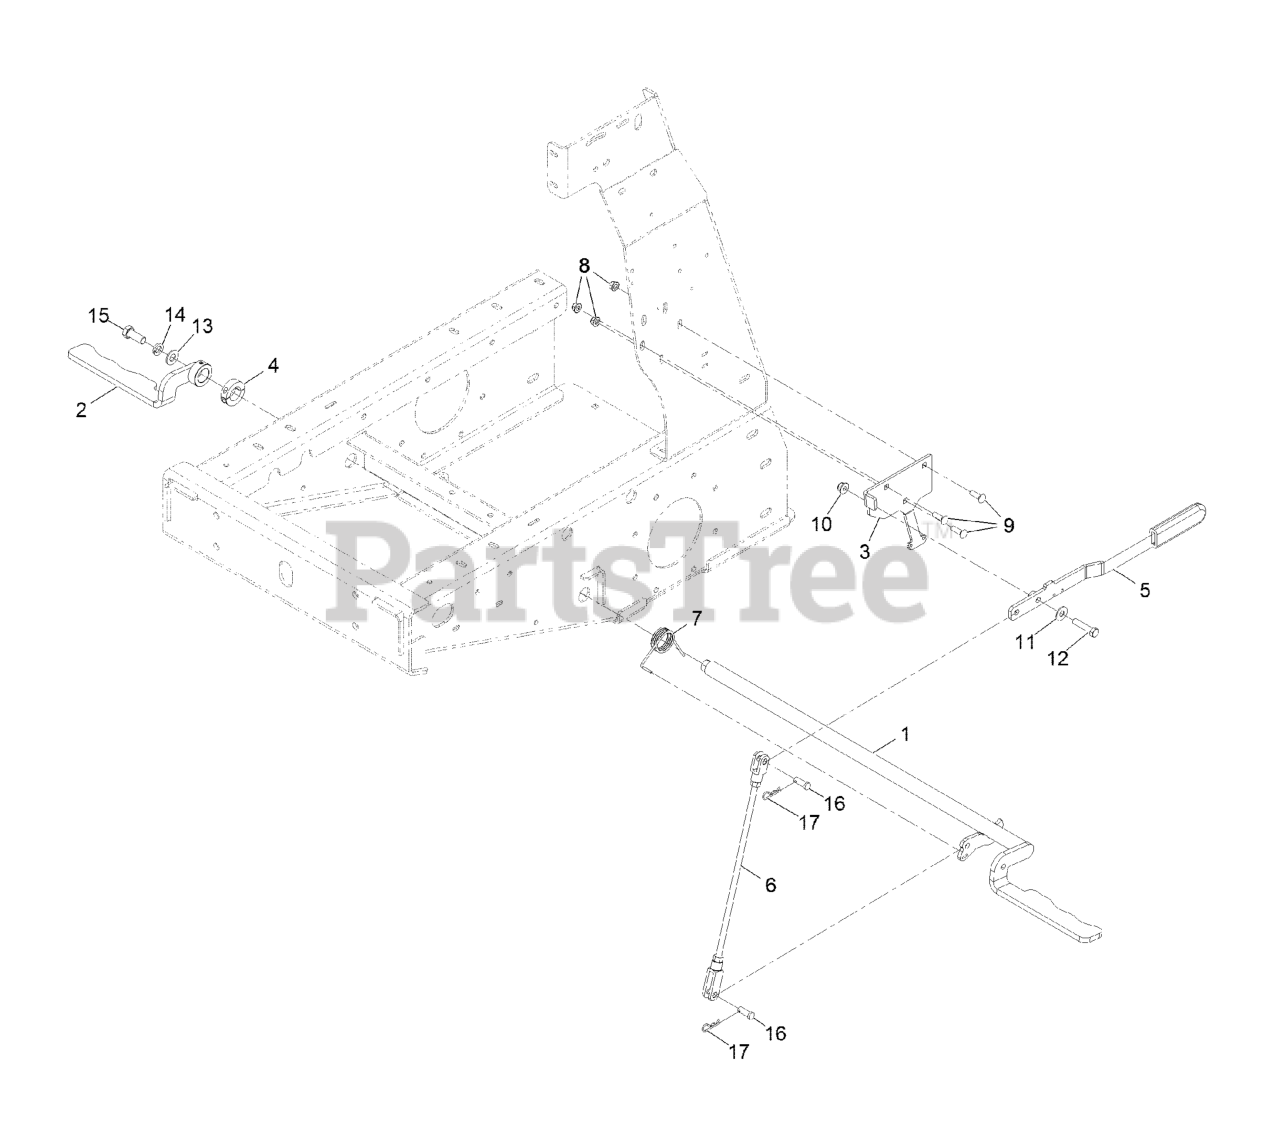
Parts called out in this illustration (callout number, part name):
1	Arm-Brake, Lt [black]
2	Arm-Brake, Rt [black]
3	BRACKET-HANDLE, BRAKE
4	COLLAR-LOCKING
5	ASM, Handle-Brake
6	ASM, Rod-Brake
7	SPRING-TORSION
8	Nut-Hex Flange
9	Bolt,Carriage,5/16-18X1,ST/ST 18-8
10	NUT-HF, NI
11	WASHER-FLAT
12	SCREW-HH
13	WASHER-FLAT
14	WASHER-LOCK
15	Screw ( .50-20Unfx1.25 Grade 8]
16	PIN-CLEVIS
17	Pin-Hair
